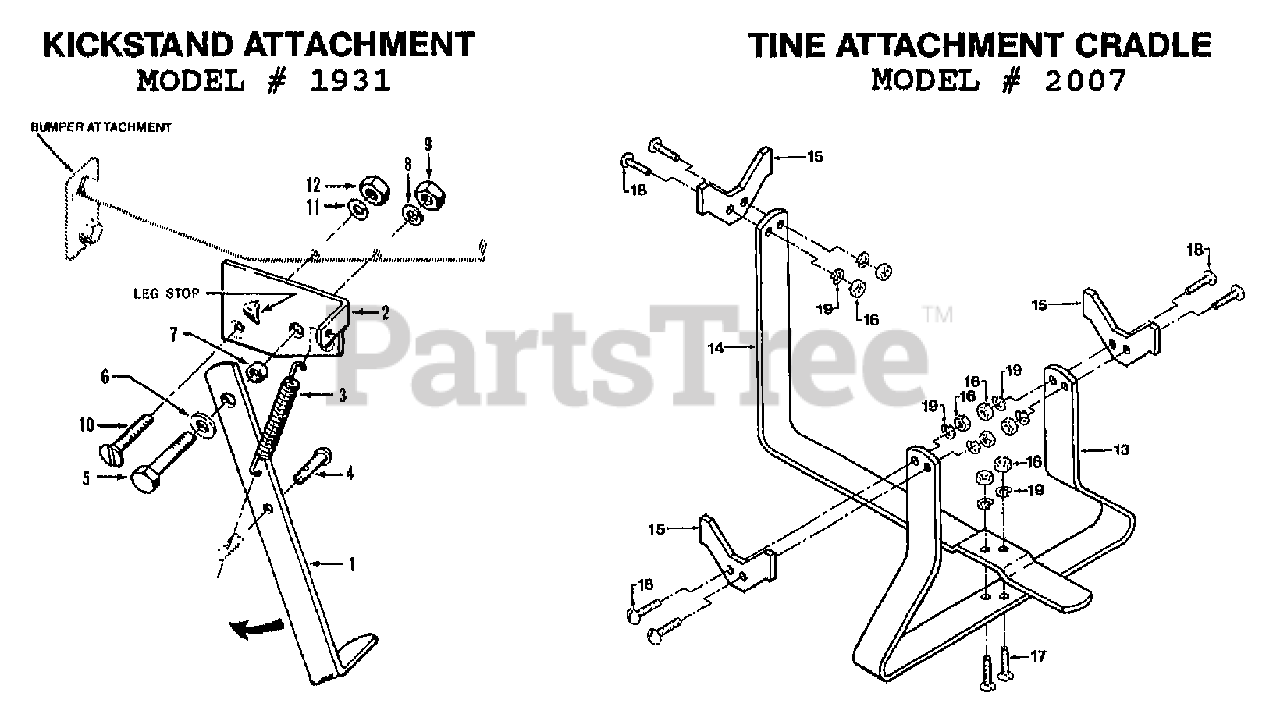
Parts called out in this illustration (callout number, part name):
1	LEG-KICK STAND PNT
2	PLATE-KICK STAND PNT
3	SPRING-.436 X 3.25
4	PIN-CLEVIS .183X1.0 ZP
5	BOLT-HH 5/16-18 X 2 G5 ZP
6	WASHER-FLAT 5/16 SAE
7	BUSHING .438X.313X.275
8	WASHER-LK .312 ZP
9	NUT-HEX 5/16-18 ZP
10	SCR-SLFH 1/4-20X1.5 ZP
11	WASHER-LK .25 ZP
12	NUT-HEX 1/4-20 ZP
13	SUPPORT-TINE CRADLE
14	SUPT-TINE CRADLE PNT
15	PLATE-TINE CRADLE PNT
16	NUT-HEX 1/4-20 ZP
17	SCR-SLFH 1/4-20 X .75 ZP
18	SCR-HH 1/4-20X.75 G5 ZP
19	WASHER-LK .25 ZP
